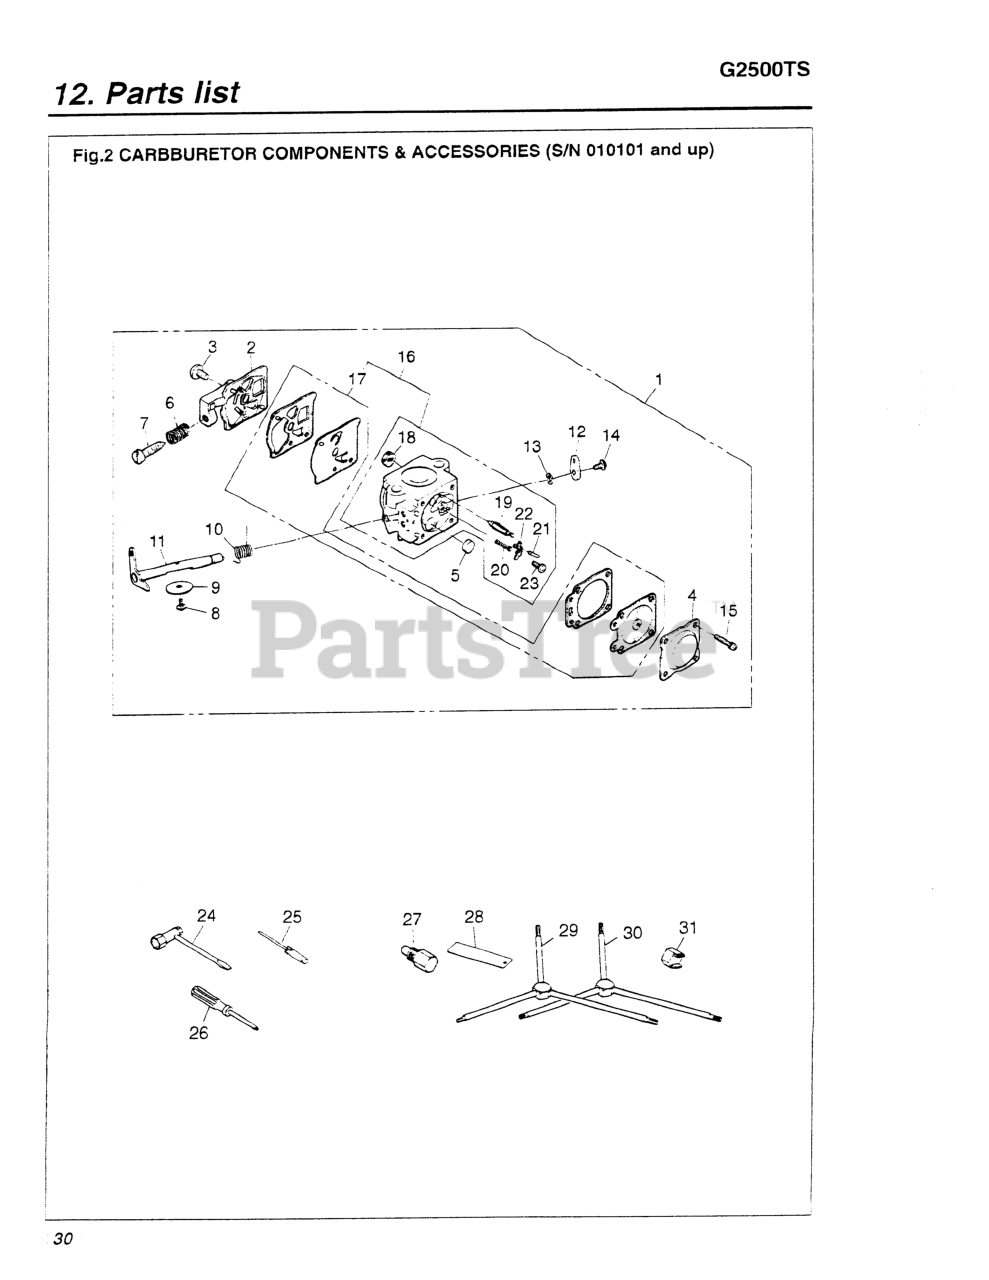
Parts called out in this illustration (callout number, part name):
1	CARBURETOR
5	PLUG, WELSH
6	SPRING, IDLE
8	SCREW (RPLS 3310-81360)
10	SPRING, RETURN
11	SHAFT ASSEMBLY
15	SCREW ASSEMBLY
16	KIT, REBUILD
18	SCREEN
19	VALVE, INLET
21	PIN
22	LEVER
23	SCREW
24	WRENCH, PLUG
25	SCREWDRIVER
26	SCREWDRIVER
27	STOPPER (TOOL) (RPLS 3320-9641
28	GUAGE, AIR GAP (TOOL)
29	HEX WRENCH (TOOL)
31	WRENCH
